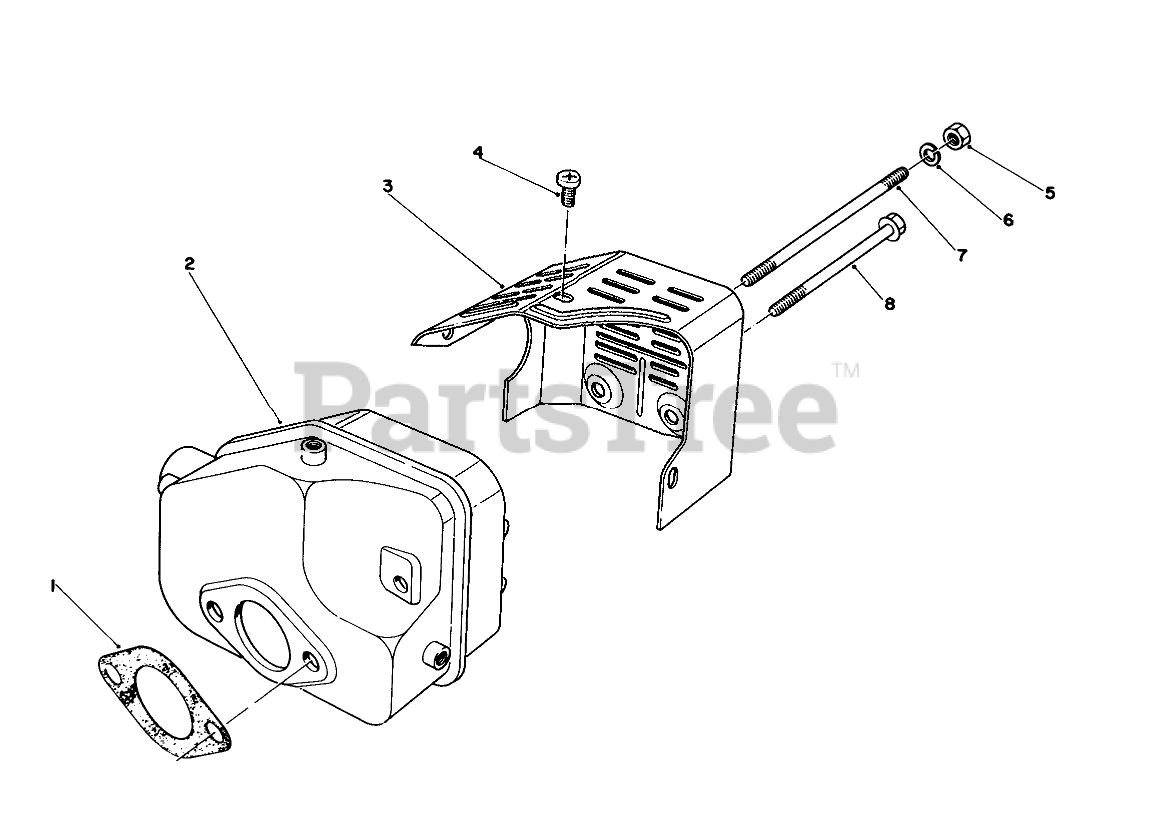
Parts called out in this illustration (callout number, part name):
1	GASKET
2	Muffler
3	COVER
4	SCREW
6	WASHER-LOCK
